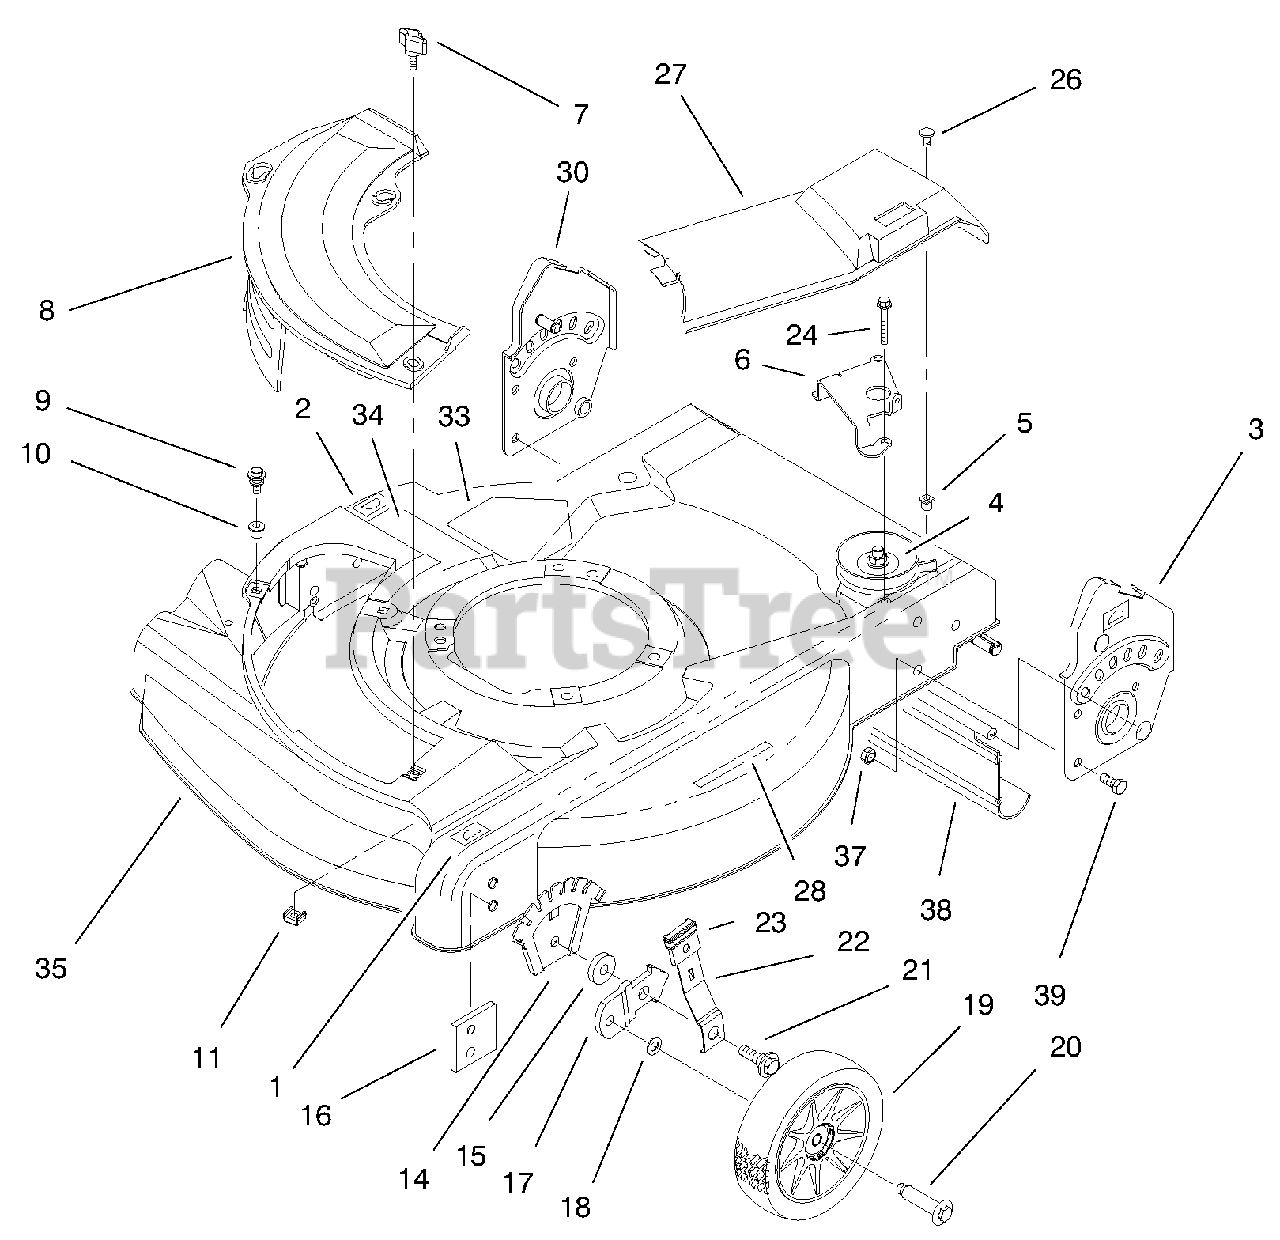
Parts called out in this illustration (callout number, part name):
1	Decal-HOC
2	Decal-HOC
3	ASM-Handle Bracket
4	ASM-Gear Case
5	Grommet
6	Guide-Transmission
7	Knob-Cover Plate
8	Mulch Plate-21"
9	Screw-Sems
10	Grommet-Plastic
11	Nut-Cage
14	Plate-Height Adjust
16	Plate-Baffle
17	Bracket-Wheel Height Adj
19	ASM-Wheel & Tire 6"
20	Bolt-Shoulder
21	Bolt-Shoulder
22	Spring Arm-Front
23	Knob-Height Adjust
24	Torx Head Cap Screw
26	Screw-Phil
27	Cover-Drive
28	Decal-Warning
30	ASM-Handle Bracket
33	Decal-Danger
34	Decal-Discharge
35	ASM-Housing & Baffle
37	Nut-Lock
38	Shield-Trailing
39	Screw-HH
